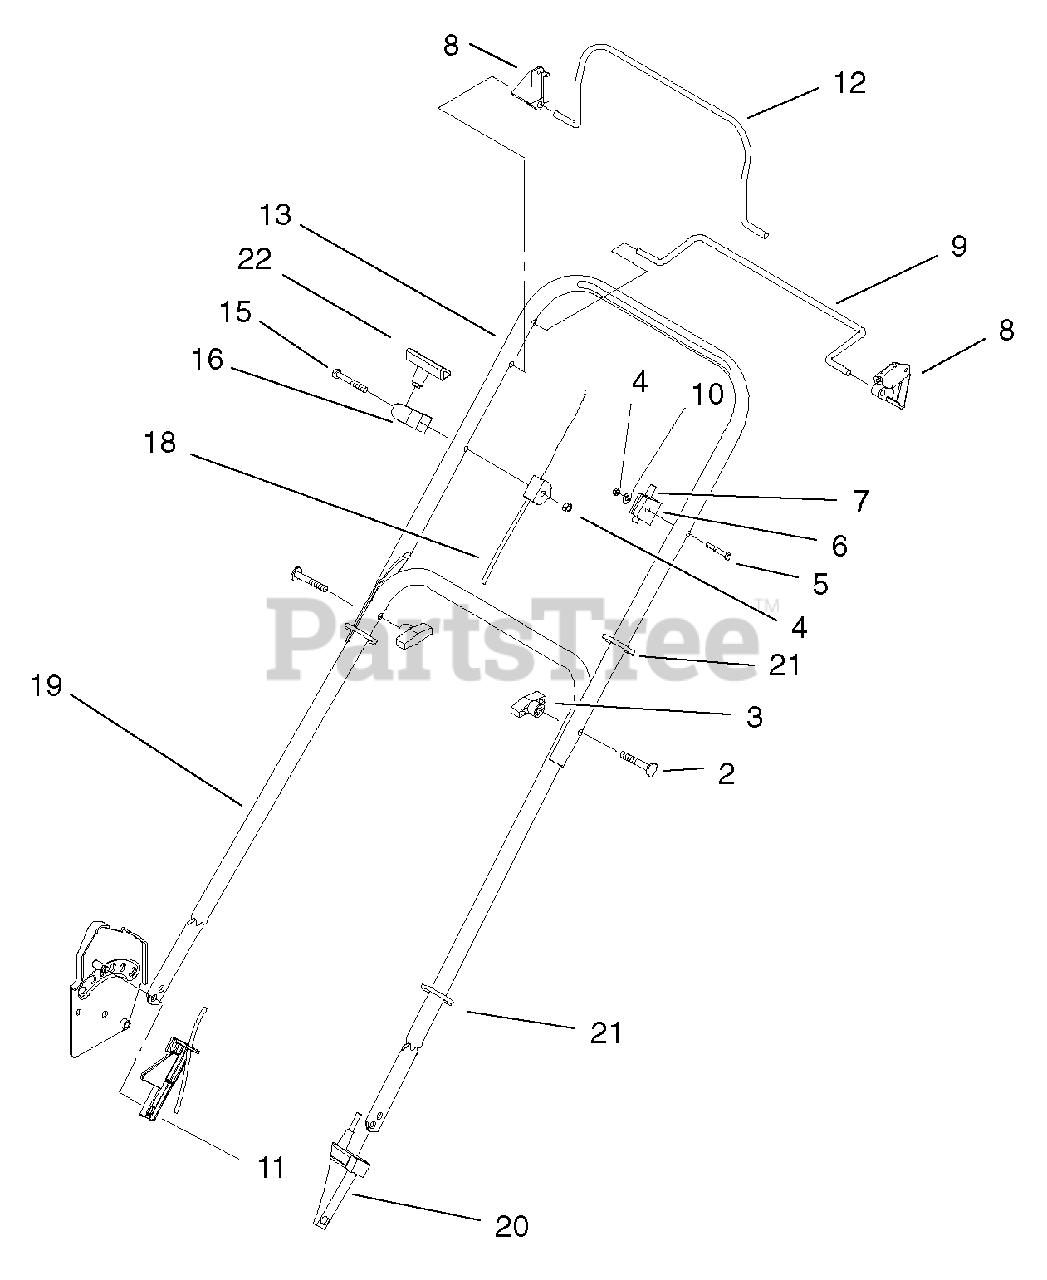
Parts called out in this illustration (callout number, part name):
3	Knob-Handle
4	Nut-Lock, NI
5	Screw-Handle
6	Anchor-Upper, Cable
7	Cable-Ground Speed
8	Stop-Pivot
9	Bail-Control
10	Washer-Flat
11	Guard-Cable
12	Bail-Brake
13	Handle-Upper
15	Screw-HH
16	Rope-Guide
18	Brake Cable ASM
19	Handle-Lower Section
20	Anchor-Cable
21	Tie Strap
22	Handle-Starter
